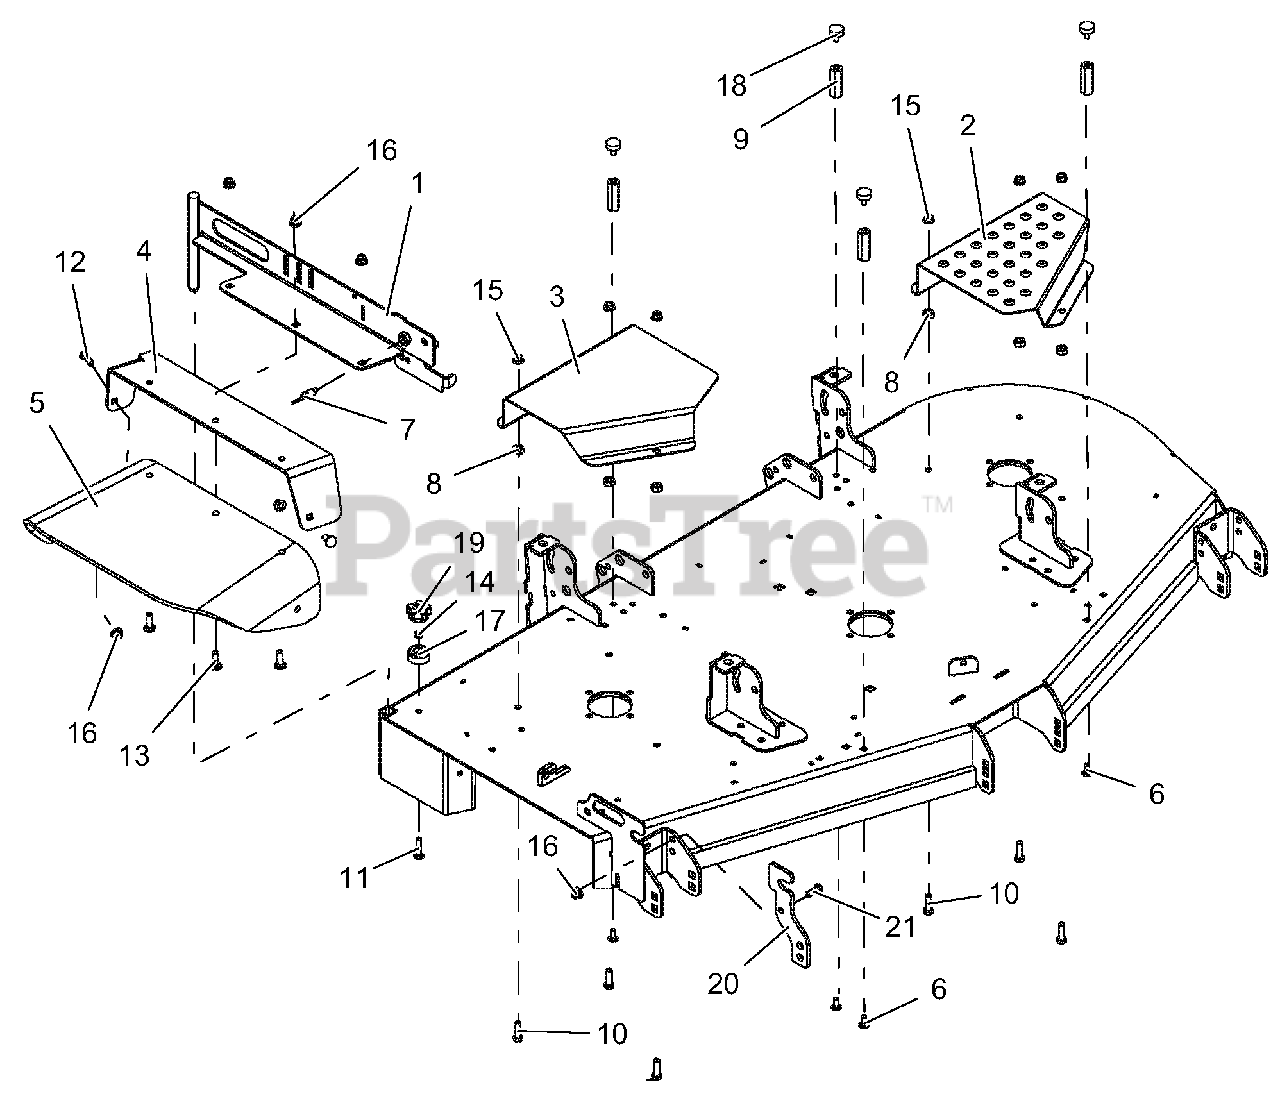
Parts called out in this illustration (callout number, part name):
1	WLDMT, 52"-60" DISCH CHUTE MTG-RED
2	GUARD, 60" LH DECK BELT-BLACK
3	GUARD, 60"-66" RH DECK BELT-BLACK
4	DISCHARGE CHUTE SUPPORT W/SAFETY DECAL-RED
5	CHUTE, RUBBER DISCHARGE
6	BLT, RDHDSQNK .31-18X.75 LOCTITE
7	PULL PIN,.50-13THDX.310 PLNGR
8	NUT-HEAVY HEX .38-16 YWZC
9	NUT, .31-18 X 2.25 LG COUPLING
10	BLT-HEX .38-16X1.25 GR5 YWZC
11	BLT-RDHDSQNK .31-18X1.50 G5 YWZC
12	BLT-RDHDSQNK .38-16X1.00 G5 YWZC
13	BLT-RDHDSQNK .38-16X1.25 G5 YWZC
14	NUT-LK-CTR .31-18 YWZC
15	@NUT-SPNLK-FLG .375-16 YWZC
16	NUT-LK-NYL-FLG .38-16 YWZC
17	BUMPER, RECESSED 1.50 X .63 W/.31 HOLE
18	BUMPER, RUBBER
19	KNOB, CLAMPING
20	CHUTE STORAGE BRACKET-RED
21	BLT-HEX .38-16X1.00 GR5 YWZC
